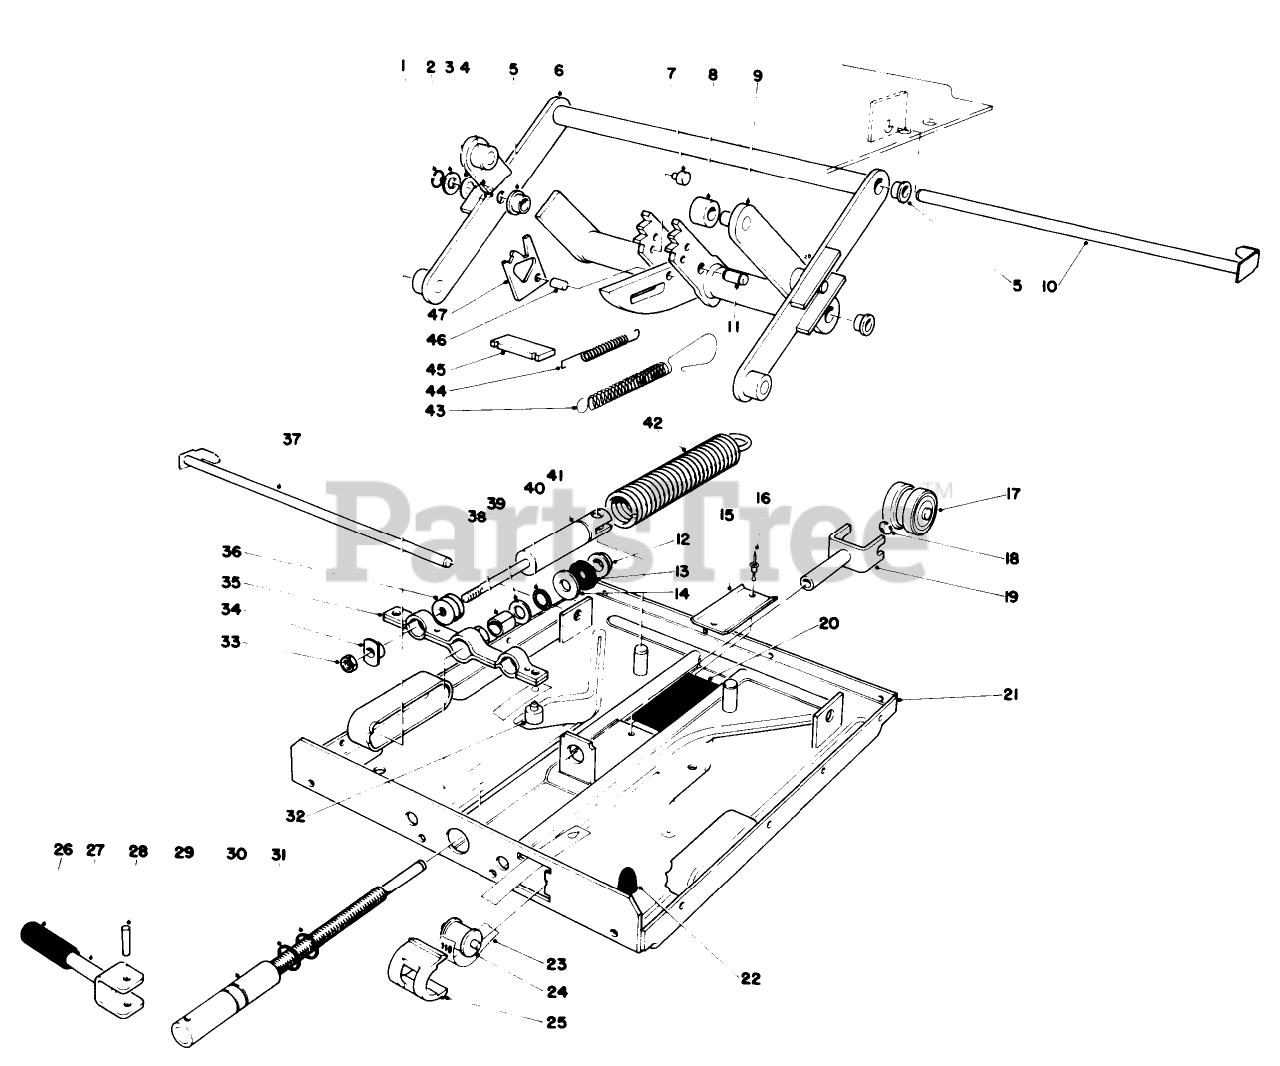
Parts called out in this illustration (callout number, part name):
1	Washer
2	Washer
5	FRONT WEIGHT *B
6	SPRING-BRAKE
11	SPRING-EXTENSION
12	Sleeve
14	Washer 8 MM
15	U-Track
16	Plate 4X10MM
17	Trible-Bearing
18	Washer
22	Bumper
26	Handle
31	Rubber Ring 14MM Red
37	SPACER-BUSHING
38	Sleeve 14x1x19MM
39	Washer
40	Thrust Needle Bearing
43	Coil Spring
45	WASHER
